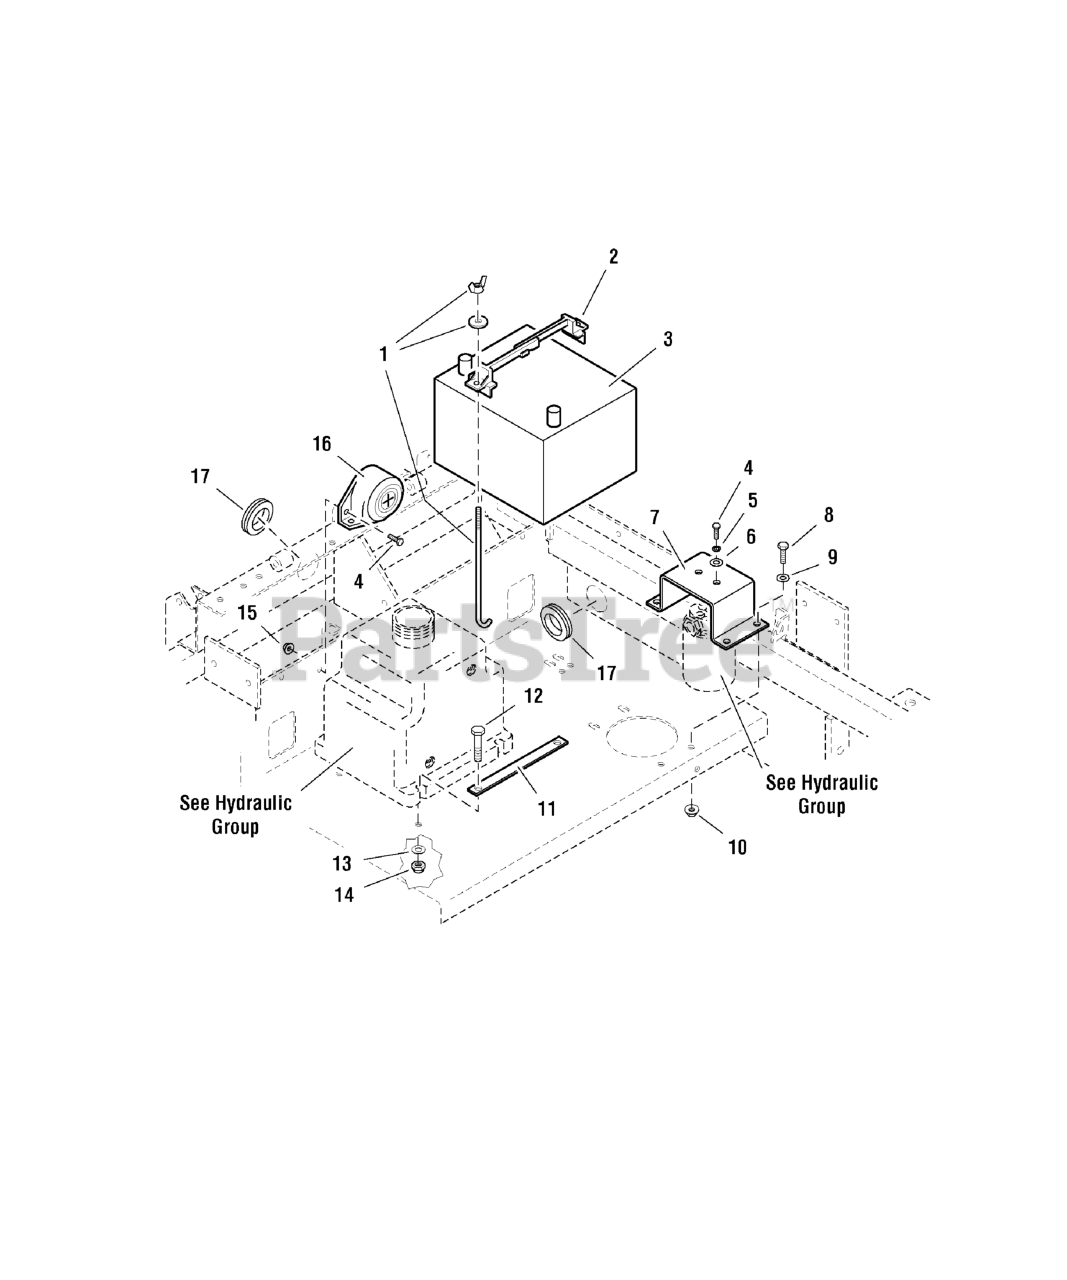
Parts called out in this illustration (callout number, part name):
1	BATTERY HOLDDOWN BOLT
2	BATTERY HOLDDOWN
3	BATTERY, 12V (BCI58, 500 CCA)
4	BOLT, 1/4-20 x 3/4
5	WASHER, 1/4 LOCK
6	WASHER, 1/4 SAE
7	OIL FILTER MOUNT
8	BOLT, 5/16-18 X 3/4 GD5
9	WASHER, 5/16" SAE
10	NUT, 5/16-18 HEX SERRATED FLANGE (SMALL)
11	HOLD DOWN PLATE
12	BOLT, 3/8-16 X 2-1/4" GD5 CZ
13	WASHER, 3/8 SAE
14	NUT, 3/8-16 HEX NYLON LOCK
15	NUT, 1/4-20 HEX SERR. FLANGE
17	GROMMET, 1-1/4"
